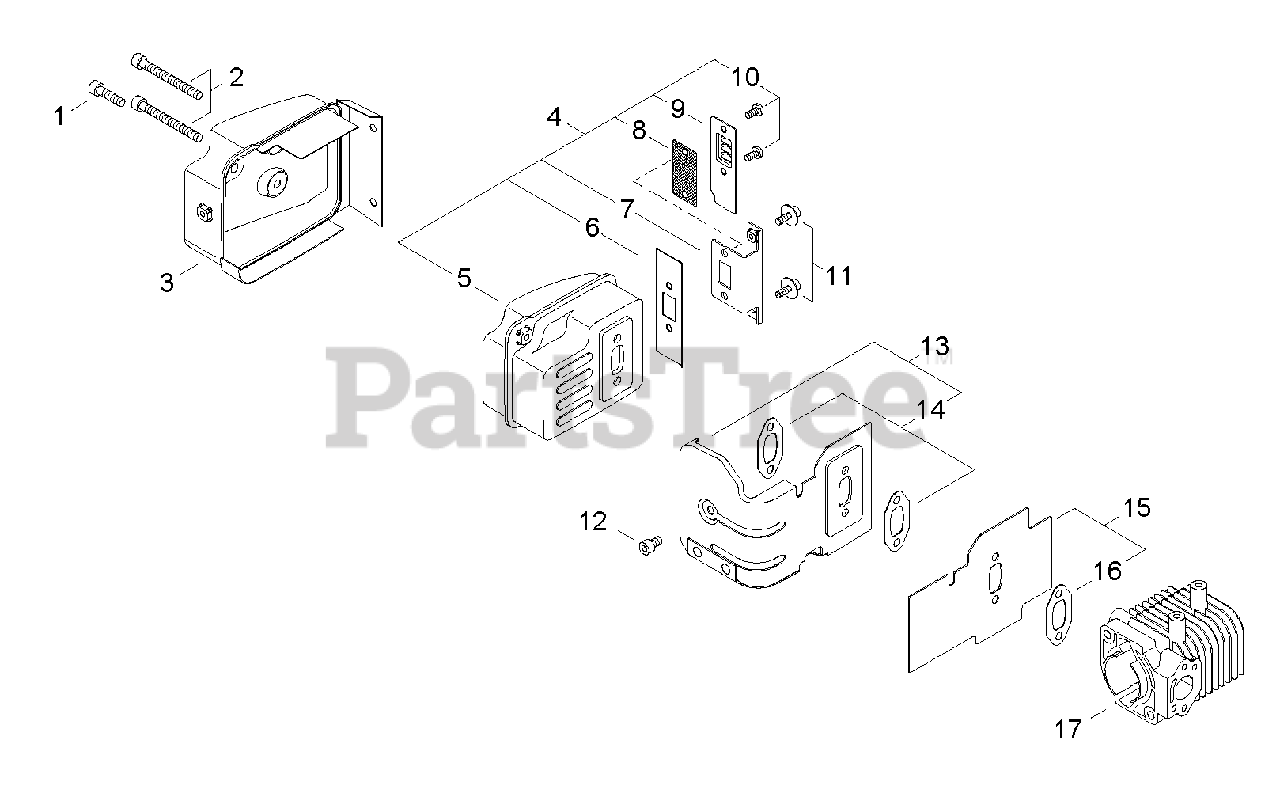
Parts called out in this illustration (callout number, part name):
1	SCREW - 5X20
2	SCREW - 5
3	COVER, MUFFLER
4	MUFFLER ASSY
5	MUFFLER
7	BRACKET, MUFFLER
8	SCREEN, SPARK ARRESTOR
9	GUIDE, EXHAUST
10	SCREW - 4X8
11	SCREW - 4X8
12	SCREW - 5X8
13	HEAT SHIELD KIT
14	HEAT SHIELD KIT
15	EXHAUST SHIELD KIT
16	HEAT SHIELD KIT
17	CYLINDER
